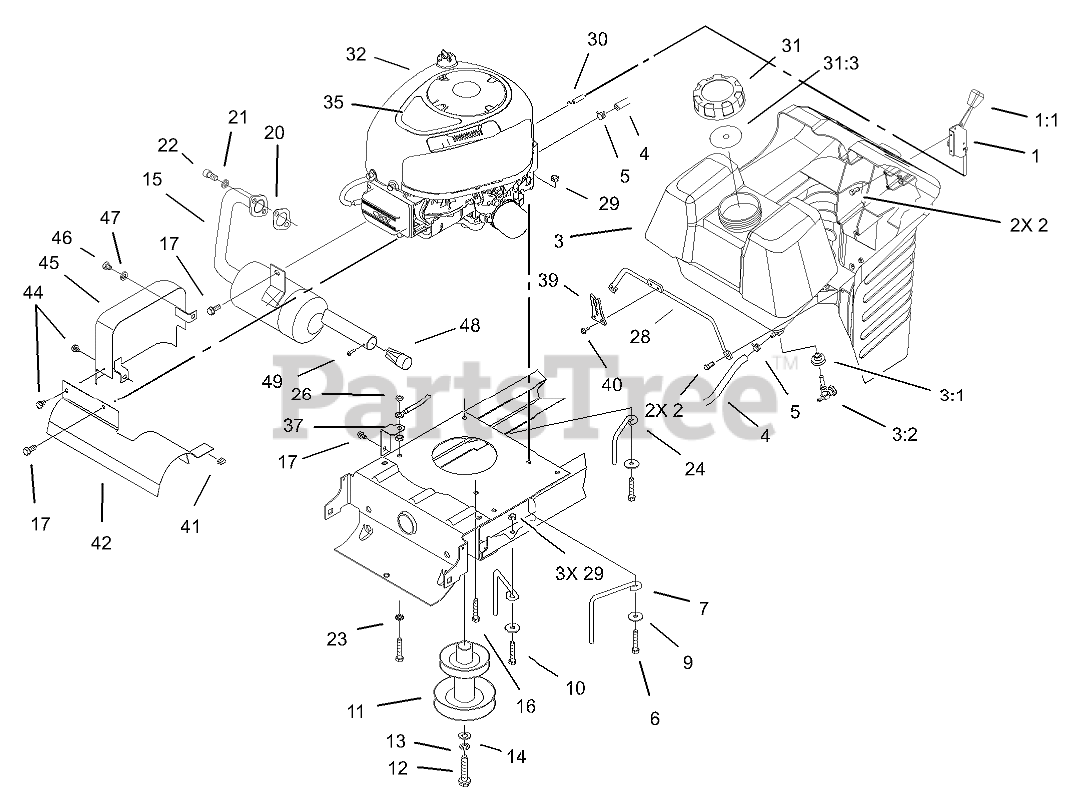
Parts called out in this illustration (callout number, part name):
1	THROTTLE CONTROL ASM
2	SCREW-SPECIAL
3	GAS TANK ASM
3:1	BUSHING
3:2	VALVE-FUEL
4	HOSE-FUEL
5	CLAMP-HOSE
6	SCREW-HH
7	GUIDE-BELT, ENGINE
9	WASHER-PIVOT
10	SCREW-HH
11	PULLEY-ENGINE
12	SCREW-HH
13	WASHER-LOCK
14	WASHER-FLAT
15	MUFFLER
16	SCREW-HWH, TAPTITE
17	SCREW-HWH
20	GASKET-EXHAUST
21	WASHER-LOCK
22	SCREW-HSH
23	WASHER-LOCK
24	GUIDE-BELT, RH
26	NUT-KEPS
28	ROD-TANK, GAS
29	NUT-LOCK, NI
30	THROTTLE CABLE ASM
31	GAS CAP ASM
31:3	GASKET-CAP, GAS
35	DECAL-ENGINE
37	BRACKET-GROUND
39	LATCH-HOOD
40	SCREW-HWH
41	CLIP-TINNERMAN
42	SHIELD-MUFFLER
44	SCREW-HWHTF
45	HEAT SHIELD ASM
46	SCREW-HH
47	WASHER-LOCK
